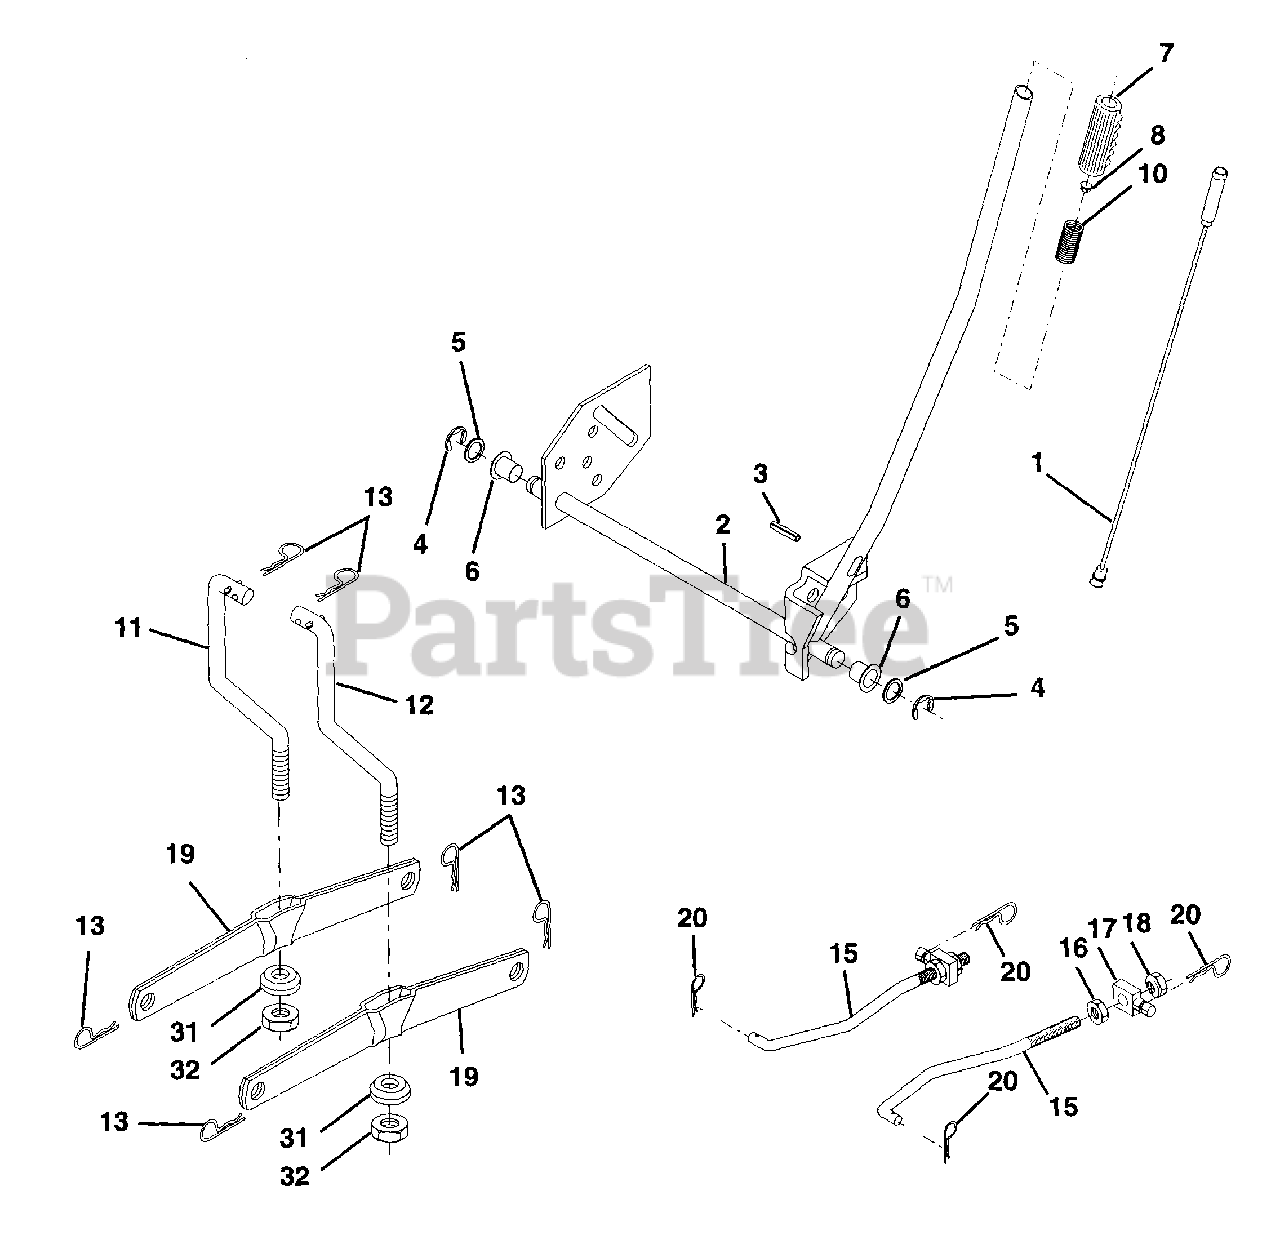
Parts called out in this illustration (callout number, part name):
1	Wire Asm Inner W/plunger 17 32
2	Shaft Asm Lift
3	Pin Groove
4	E Ring #5133-62
5	Washer PLTD 21/32 X 1 X 21 ga
6	Bearing Nylon Blk 629 Id
7	Grip Handle Bicycle
8	Button Plunger Black
10	Spring Cprsn 3 750 Oiled
11	Link Lift LH
12	Link Lift RH
13	Retainer Spring
15	Link Front
16	Nut Jam Hex 1/2-13 Unc
17	Trunnion Blk Zinc
18	Nut Lock W/wsh 1/2-13 unc
19	Arm Suspension Rear
20	Spring, Retainer
31	Bearing Pvt. Lift Spherical
32	Nut Crownlock 3/8-24
